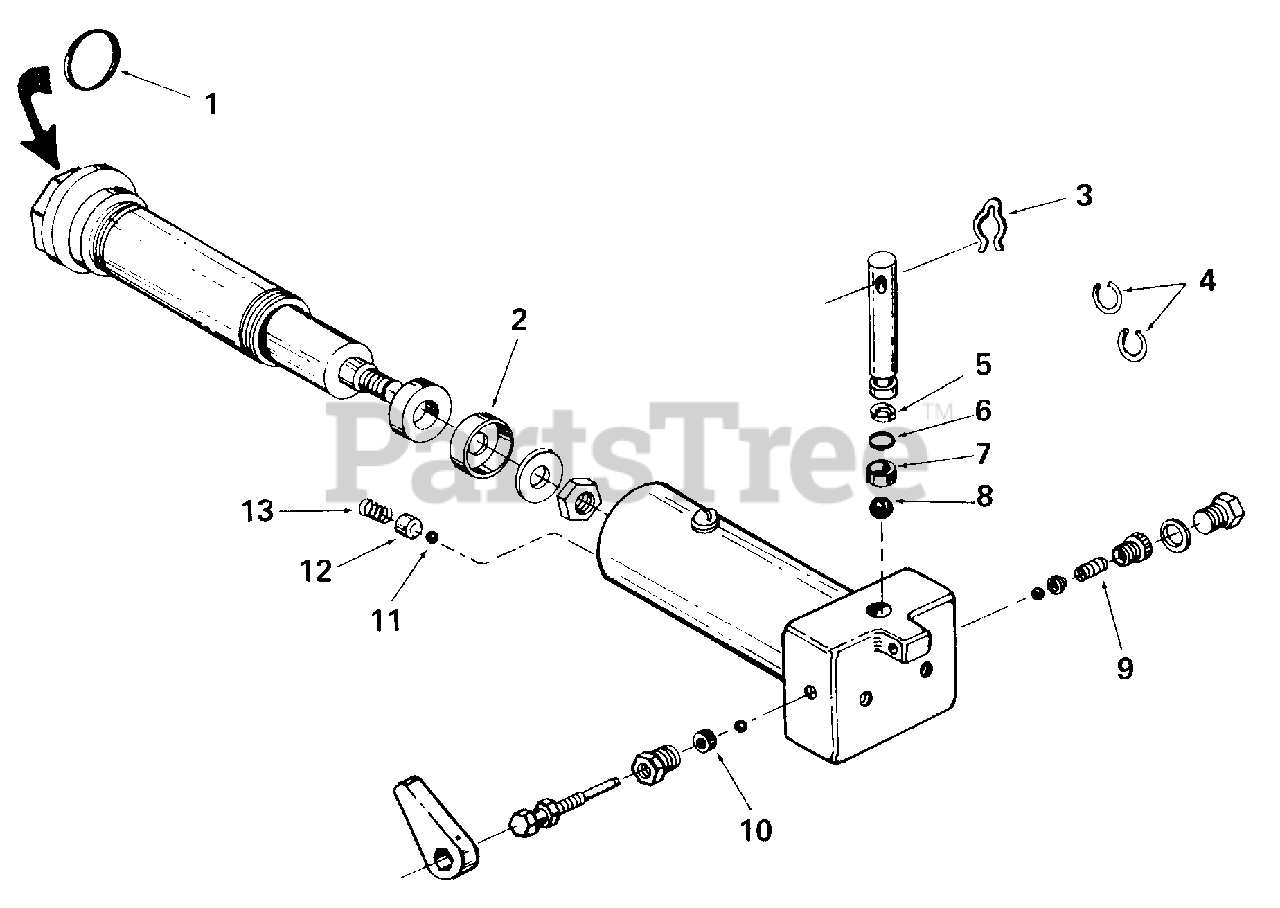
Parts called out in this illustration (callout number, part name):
1	Quad Ring
2	Cup
3	Hair Pin Clip
4	Pin Ring
5	Back-Up Washer
6	"O"-Ring
7	Ball Retainer
8	Ball
9	Spring
10	Packing
11	Ball
12	Ball Retainer
13	Spring
